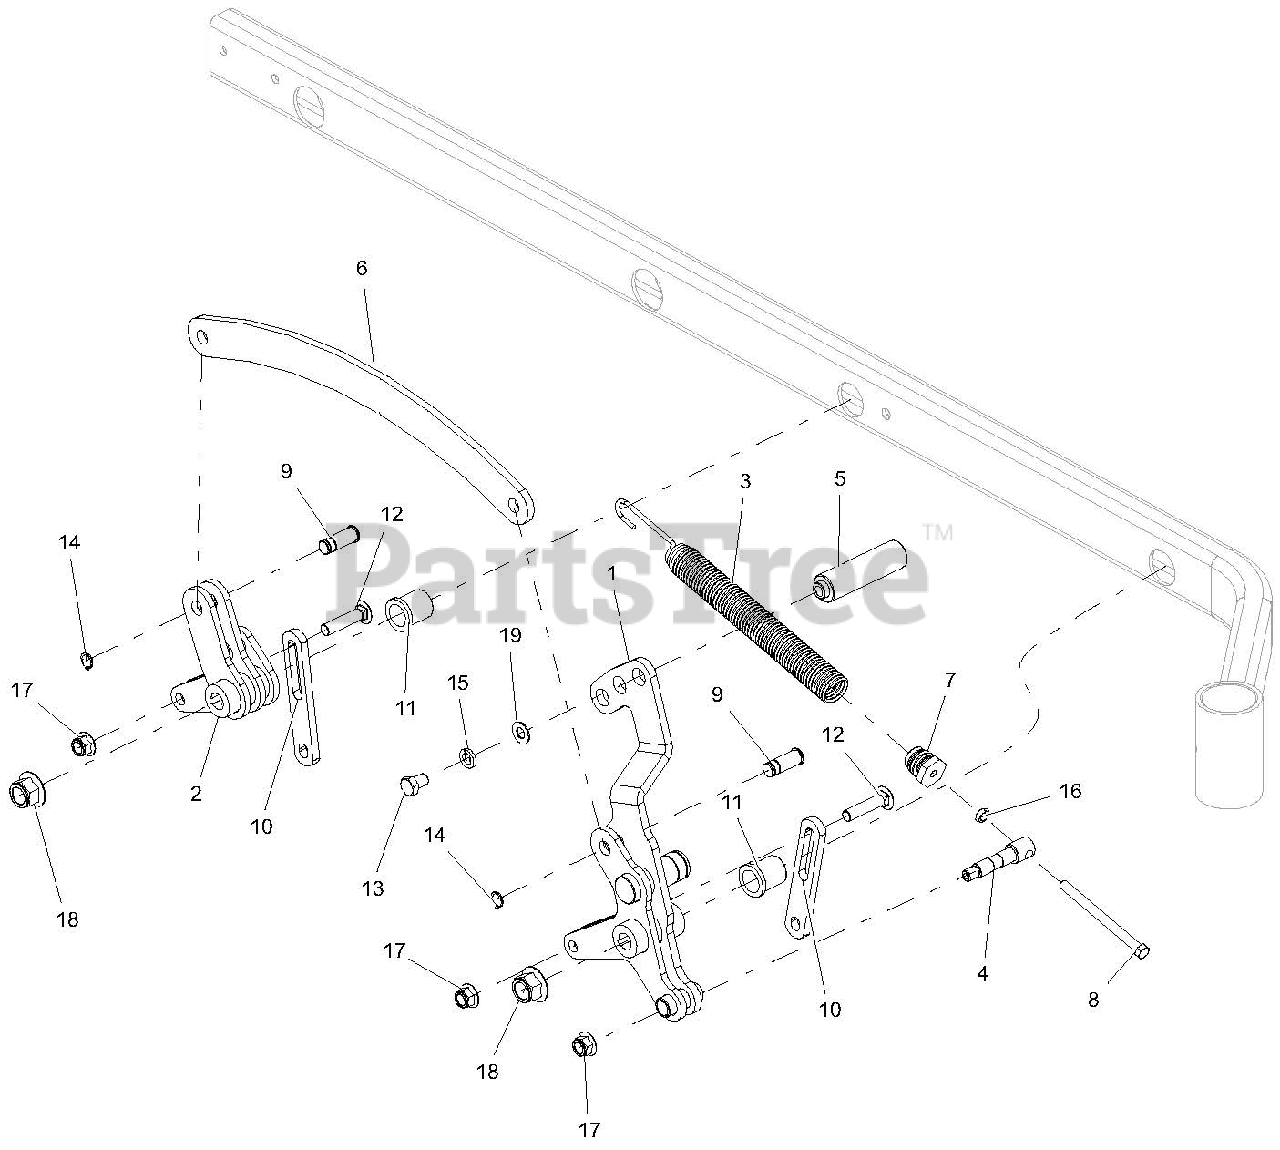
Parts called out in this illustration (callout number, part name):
1	WLDMT, PT400 FRONT RH DECK LIFT ARM-BLACK
2	WLDMT, PT400 REAR RH DECK LIFT ARM-BLACK
3	SPRG, DECK LIFT
4	TRUNION, SPRG
5	PEDAL, LIFT
6	LIFT, LINK - BLACK
7	PLUG, SPRG
8	BLT-HEX .38-16X5.00 GR5 YWZC
9	PIN, CLEVIS .625 SNAP RING
10	LINK, DECK LIFT - LONG
11	BSHG-FLG 1.00X1.25X1.5X1.5
12	BLT-RDHDSQNK .50-13X2.25 G5Y
13	BLT-HEX .50-13X.75 GR5 YWZC
14	RG-RTNG-EXT .625x.050
15	WSHR-LK .50X.125 REG YWZC
16	NUT, JAM .375-16 YWZC
17	NUT-LK-NYL-FLG .50-13 YWZC
18	NUT-LK-NYL-FLG .75-10 YWZC
19	WSHR-FL-STL .505X1.00X.062 YWZC
